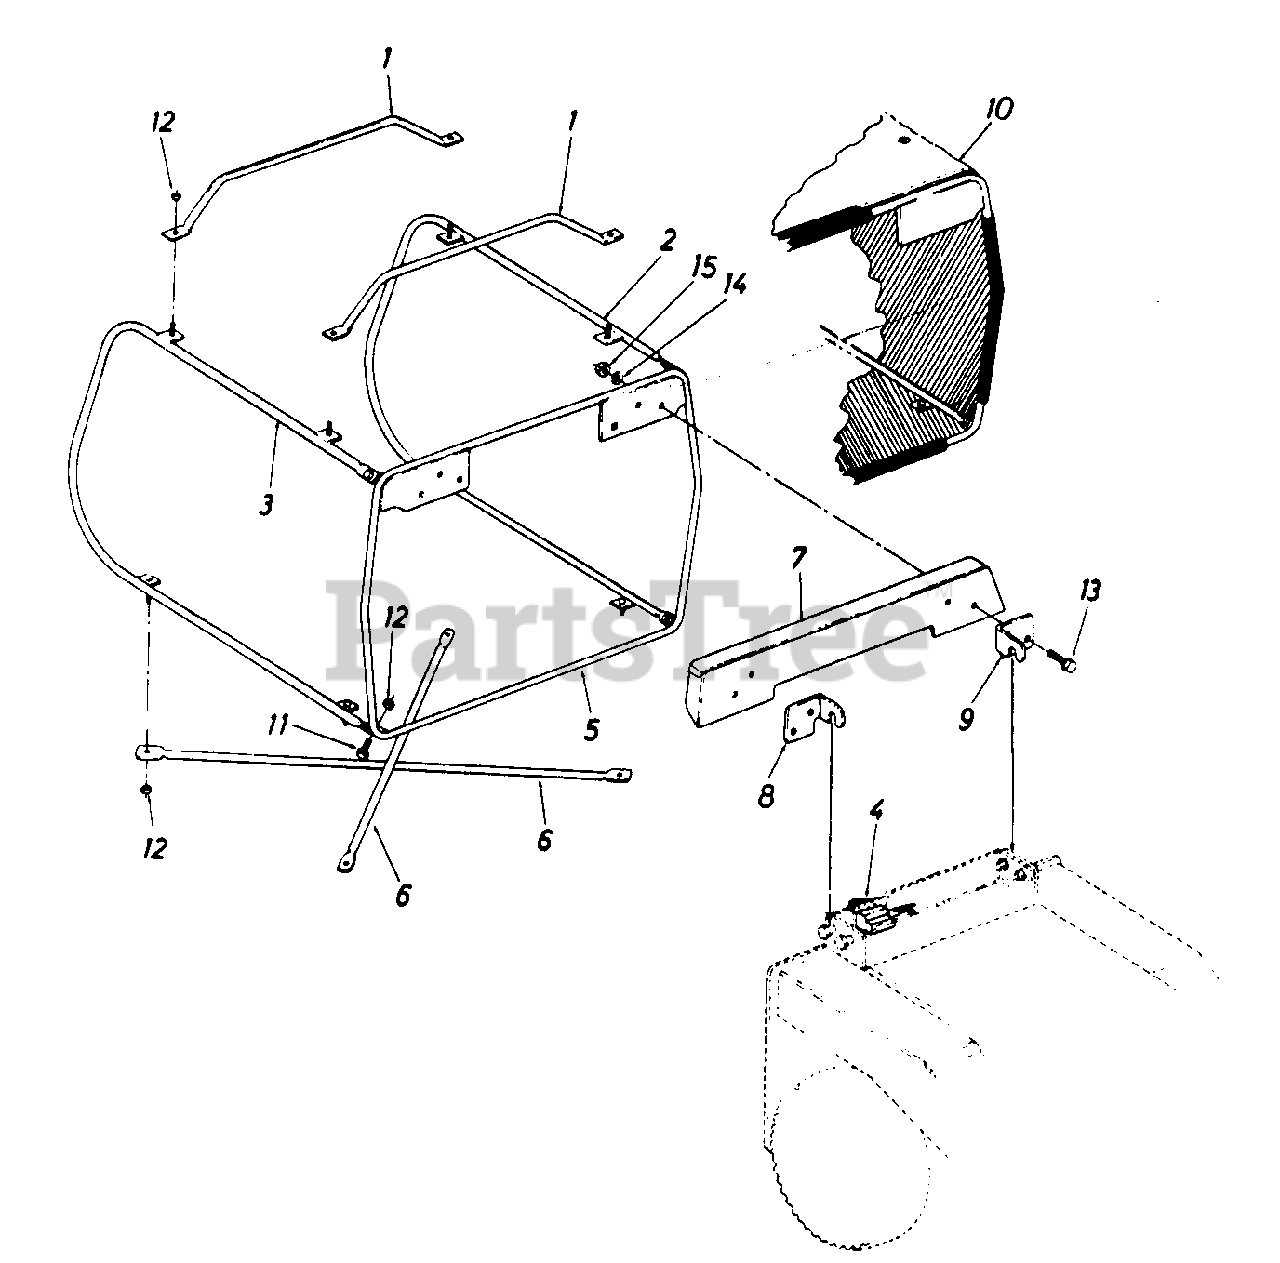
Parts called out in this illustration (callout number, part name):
1	Catcher Handles
2	Catcher Side Frame Ass'y. L.H.
3	Catcher Side Frame Ass'y. R.H.
4	Safety Switch
5	Catcher Frame Ass'y.
6	Bottom Cross Brace
7	Dust Cover
8	Hinge-R.H.
9	Hinge-L.H.
10	Grass Bag
11	Hex Scr. 1/4-20 x .62" Lg.
12	Hex Cent. L-Nut 1/4-20 Thd.
13	Hex Sems Scr. 5/16-18 x 1.00" Lg.
14	L-Wash. 5/16" Scr.
15	Hex Nut 5/16-18 Thd
